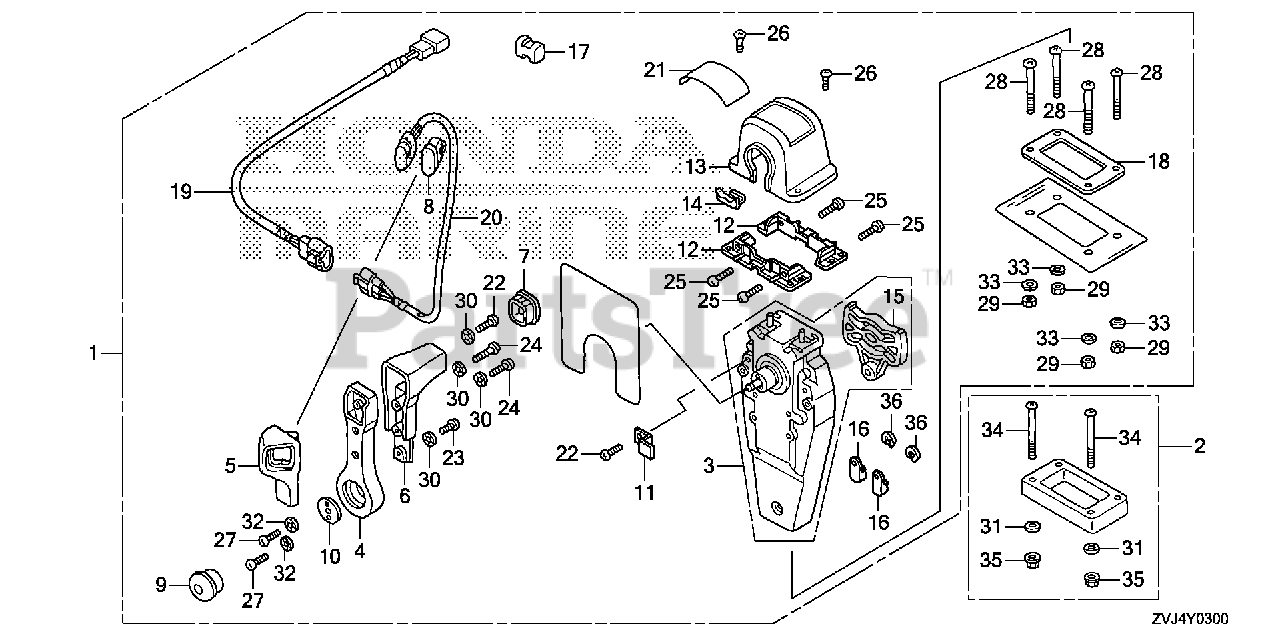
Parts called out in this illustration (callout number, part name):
1	BOX KIT, REMOTE CONTROL (TOP MOUNT SINGLE)(R)
2	SPACER KIT, REMOTE CONTROL BOX (TOP MOUNT SINGLE)
3	HOUSING ASSY., L. (INNER) (TOP MOUNT)
4	HANDLE, REMOTE CONTROL
5	COVER, L. GRIP
6	GRIP, REMOTE CONTROL HANDLE
7	CAP, GRIP
8	CAP, SWITCH
9	BUTTON, THROTTLE
10	PLATE, HANDLE
11	PLATE, CABLE CLAMP
12	BRACKET, REMOTE CONTROL HOUSING
13	HOUSING, REMOTE CONTROL BOX
14	HOUSING, LEAD
15	PLATE, DWELL
16	TERMINAL, CABLE
17	SPACER, CABLE CLAMP
18	GASKET, SINGLE
19	SUB-HARNESS ASSY., POWER TRIM-TILT (A)
20	SWITCH ASSY., POWER TRIM-TILT (A)
21	MARK, REMOTE CONTROL (SINGLE)
22	SCREW, PAN (5X16)
23	SCREW, PAN (5X10)
24	SCREW, PAN (5X20)
25	SCREW, PAN (5X18)
26	SCREW, PAN (4X10)
27	SCREW, PAN (6X18)
28	SCREW, PAN (5X40)
29	NUT, HEX. (5MM)
30	WASHER, LOCK (5MM)
31	WASHER, PLAIN (5MM)
32	WASHER, LOCK (6MM)
33	WASHER, PLAIN (5MM)
34	SCREW, PAN (5X65)
35	NUT, HEX. (5MM)
36	E-RING (6MM)
